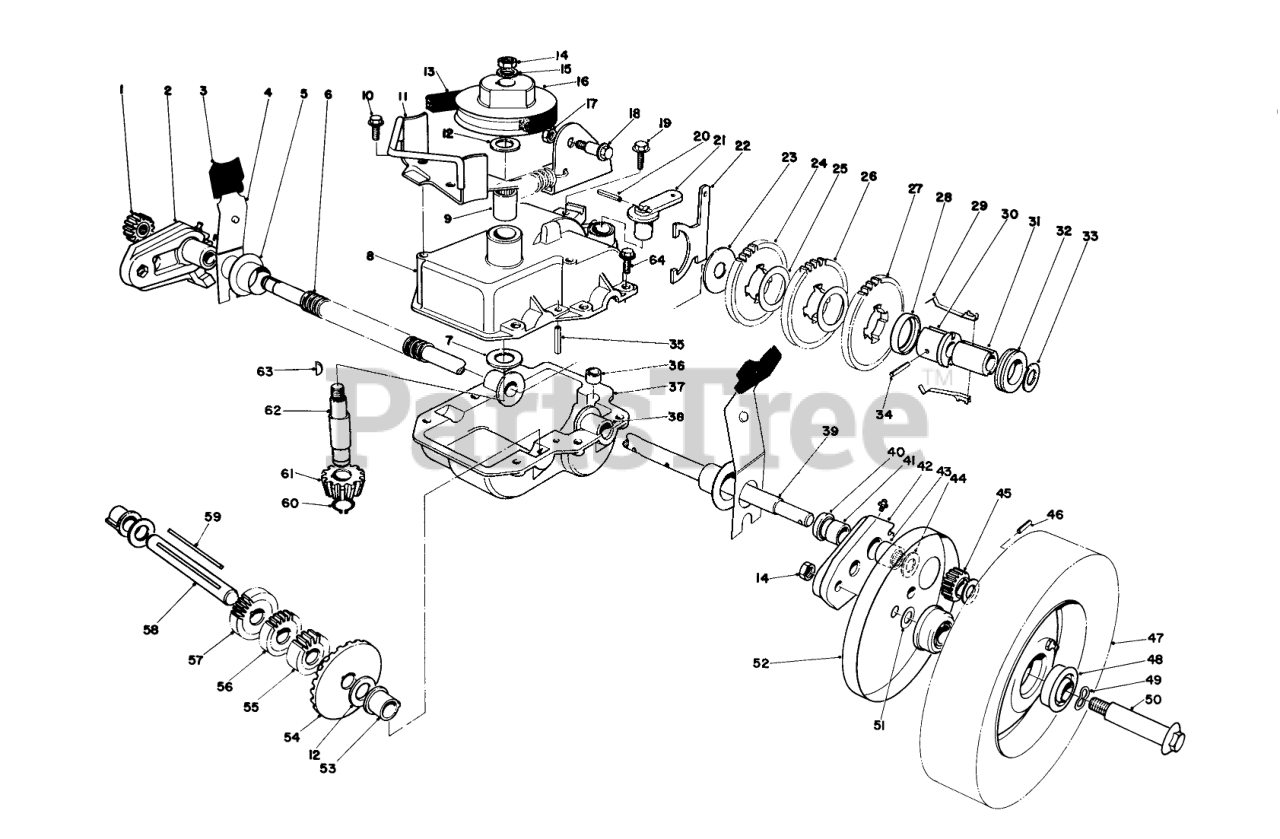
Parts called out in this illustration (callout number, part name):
1	RH CLUTCH & PINION
2	Pivot Arm R.H. (Incl. Ref. #40, 41 & 43)
3	KNOB-ARM
4	Spring Arm
5	CAP-END
6	CONDUIT-CONVOLUTED, SPLIT
7	Thrust Washer
8	Case-Upper
9	Bearing
10	Screw
11	Belt Guide Bracket
12	WASHER-THRUST
13	V-BELT
14	Nut
15	WASHER-FLAT
16	Pulley
17	NUT-HEX, SIDE DEFORM
18	Shoulder Bolt
19	SCREW-HWHTF
20	PIN-COIL
21	LEVER-SHIFT
22	Shift Yoke
23	WASHER
24	Gear 35 Tooth
25	WASHER
26	Gear 37 Tooth
27	GEAR-42T
28	KEY RETAINER
29	Key
30	Body-Sleeve
31	SLEEVE
32	COLLAR-SHIFT
33	WASHER-PLAIN
34	PIN-SPRING
35	ROLL PIN 3/16 X 1 IN
36	BUSHING-YOKE
37	LOWER GEAR CASE CAST
38	Bushing
39	OUTPUT SHAFT
40	Seal
41	Bushing
42	Pivot Arm L.H. (Incl. Ref. #40, 41 & 43)
43	Needle Baring
44	WASHER
45	LH CLUTCH & PINION
46	Coil Pin
47	Wheel & Tire Assy. (Incl. Ref. #48)
48	BEARING-BALL
49	SPRING WASHER
50	WHEEL BOLT
51	WASHER
52	Cover-Wheel
53	Botching Shaft
54	BEVEL GEAR
55	14 T GEAR
56	Gear 19 Tooth
57	Gear 21 Tooth
58	Sort Shaft
59	Key Square
60	RING-RETAINING
61	PINION-BEVEL
62	INPUT SHAFT
63	KEY-WOODRUFF
64	SCREW-HWH, THREAD ROLL
